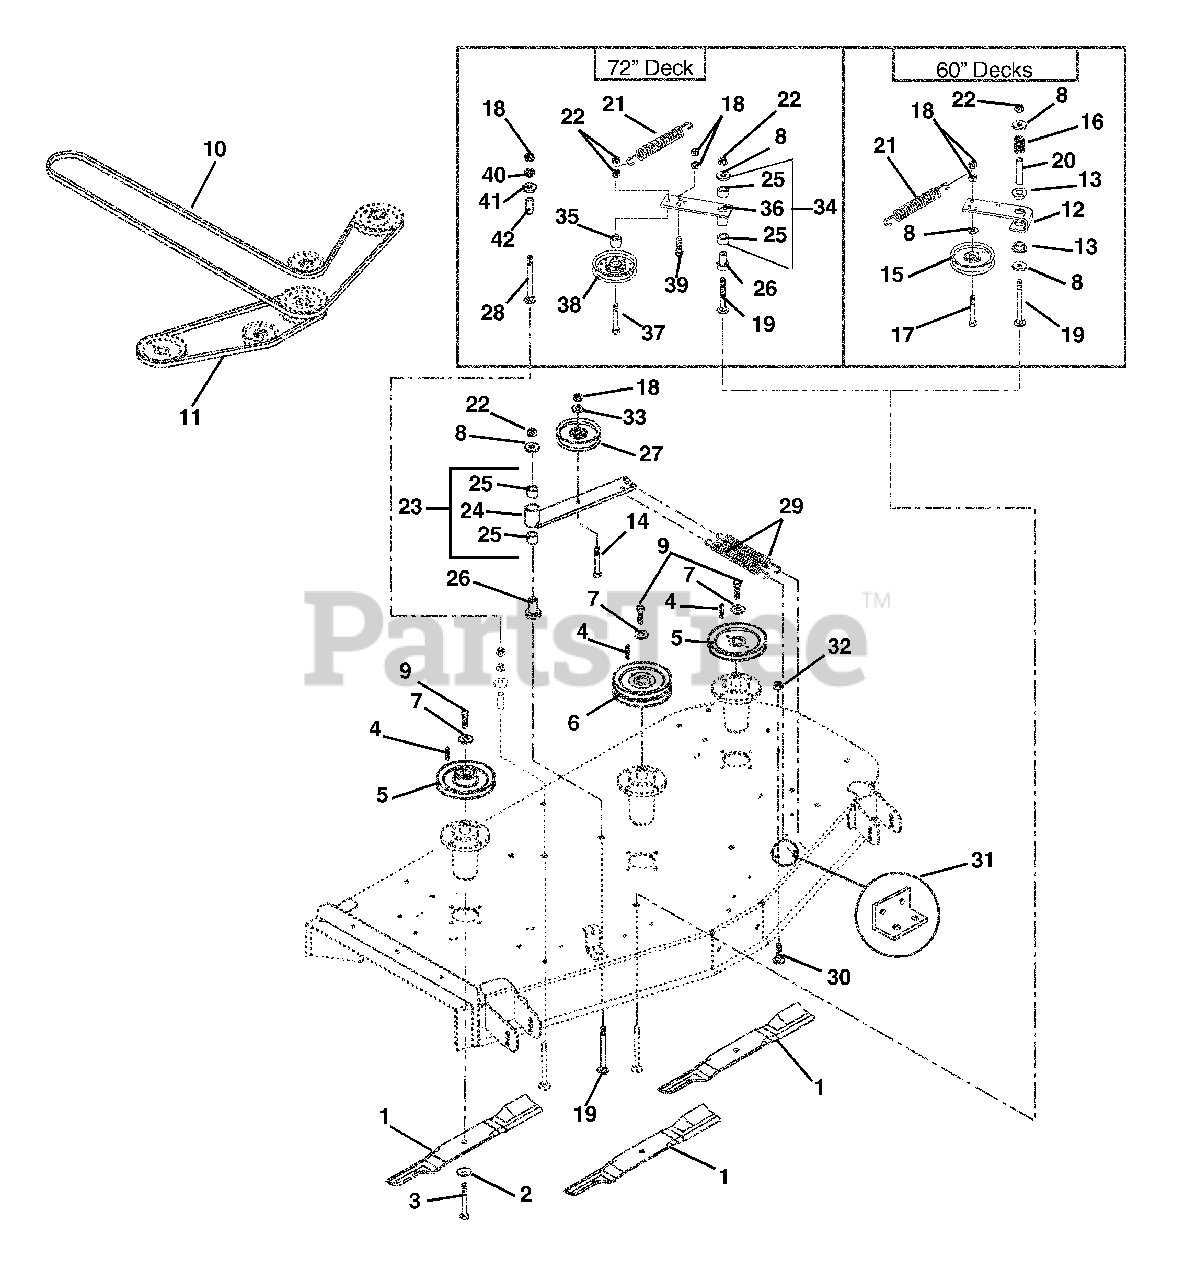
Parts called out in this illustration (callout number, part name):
1	Blade, Mower-72" Without Tungsten Carbide Hardfacing (036, 038, 039)
1	Blade, 60" Mower (036, 038, 039)
1	Blade, 60" Mulching Tungsten (036, 038, 039)
1	Blade, 72" Mulching Tungsten (036, 038, 039)
1	Blade 60" Mower CE (309)
2	Washer-Bellville .63 x 1.625 x .14
3	Bolt-Hex .62-18 x 1.75 Grade 8
4	Key-Straight .25 x 1.00 x .25
5	Weldment, Spindle Sheave 7.00 (037, 039)
5	Weldment, Spindle Sheave 6.00 (036, 038, 309)
6	Weldment, Sheave (Double) 7.25 (037, 039)
6	Weldment, Spindle Sheave (Double) 6.25 (036, 038, 309)
7	Washer, Cupped, Serrated .375
8	Washer-Flat-Steel .531 x 1.25 x .100 (037, 039)
8	Washer-Flat-Steel .531 x 1.25 x .100 (036, 038, 309)
9	Bolt-Hex .38-16 x 1.00 Grade 8
10	V-Belt, B-RMA 69.81 x .625 (037, 039)
10	V-Belt, B-RMA 63.40 x .625 (036, 038, 309)
11	V-Belt, B-RMA 28.62 x .625 (037, 039)
11	V-Belt, B-RMA 23.94 x .625 (036, 038, 309)
12	Arm, Idler Pivot (036, 038, 309)
13	Bushing, Flange Nylon .762 x 1.0 x .58 x 1.48 (036, 038, 309)
14	Bolt, Round Head Square Neck .38-16X2.75 Grade 5
15	Idler-V 4.00 x .377 (036, 038, 309)
16	Spring-Compression .085 x .80 x 1.00 (036, 038, 309)
17	Bolt-Hex .38-16 x 2.25 Grade 5 (036, 038, 309)
18	Nut-Locking-Center .38-16 (036, 038, 309)
18	Nut-Locking-Center .38-16 (037, 039)
19	Bolt-Round Head Square Neck .50-13 x 3.50
20	Spacer .560 x .750 x 2.437 Steel (036, 038, 309)
21	Spring, Extension
22	Nut-Locking-Center .50-13 (037, 039)
22	Nut-Locking-Center .50-13 (036, 038, 309)
23	Assembly, Idler Pivot Arm
24	Weldment, Idler Pivot Arm
25	Bearing, 1.00 x 1.12 x .75
26	Bearing, Pedistal Powdered Metal (037, 039)
26	Bearing, Pedistal Powdered Metal (036, 038, 309)
27	Idler-Flat 4.00 x .38 (2.00 W)
28	Bolt-Round Head Square Neck .38-16 x 2.75 Grade 5
29	Spring, Extension
30	Bolt-Round Head Square Neck .38-16 x 1.00 Grade 5
31	Bracket, Spring (036, 037)
31	Bracket, Spring (038, 039, 309)
32	Nut-Locking-Nylon .38-16
33	Washer-Flat-Steel .375 x 1.125 x .065
34	Assembly, Idler Arm-Ground Drive
35	Spacer .51 x .75 x .62 (037, 039)
36	Weldment, Idler Arm Ground Drive (037, 039)
37	Bolt-Hex .50-13 x 2.50 Grade 5 (037, 039)
38	Idler-Flat-Pulley 6.75 x .510 (037, 039)
39	Bolt-Hex .38-16 x 1.25 Grade 5 (037, 039)
40	Nut-Locking-Nylon .38-16 (037, 039)
41	Washer-Flat-Steel .406 x .812 x .065 (037, 039)
42	Spacer .380 x .625 x 1.50 (037, 039)
